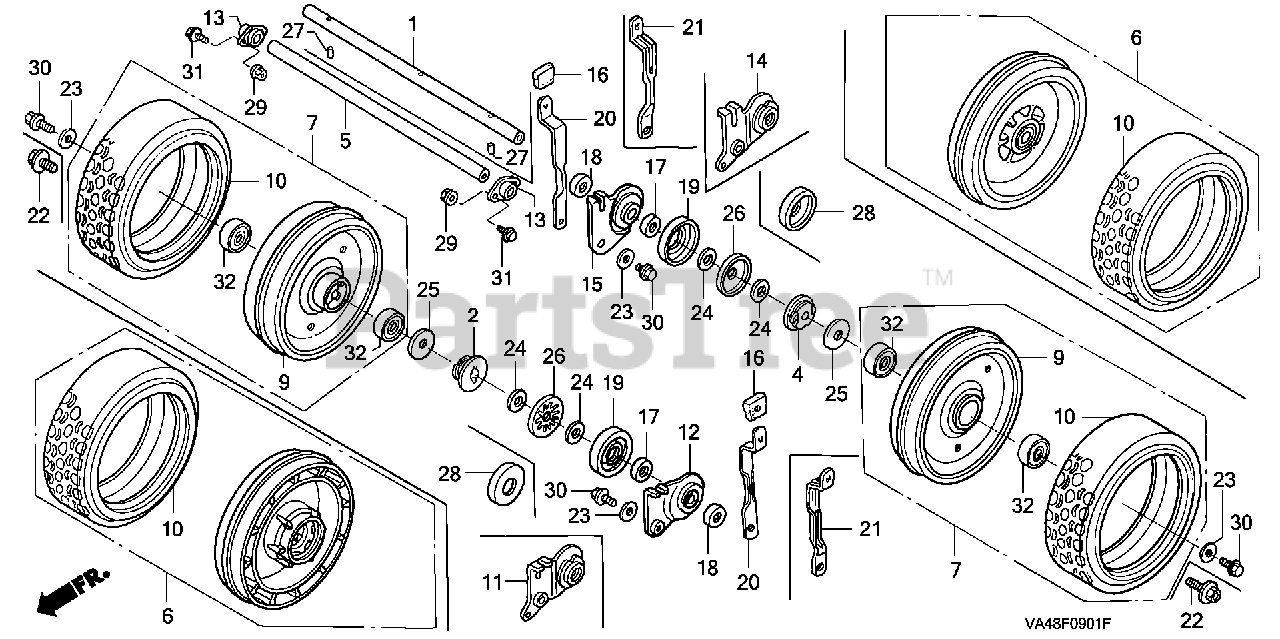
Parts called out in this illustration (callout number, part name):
2	HOLDER, R. RATCHET
4	HOLDER, L. RATCHET
5	SHAFT, RR. AXLE
6	WHEEL ASSY., RR. (9") *NH192M* (GENTLY SILVER METALLIC)
11	ARM, R. RR. ADJUSTER
13	HOLDER, RR. AXLE
14	ARM, RR. ADJUSTER
16	GRIP, ADJUSTER
16	GRIP, ADJUSTER *NH105* (MAT BLACK)
17	COLLAR, DUST SEAL
18	COLLAR, DUST SEAL
20	PLATE, RR. ADJUSTER
23	WASHER, RR. ENGINE MOUNTING
24	WASHER, PLAIN (15MM)
25	WASHER (16MM)
26	SEAL, RR. WHEEL
28	COLLAR, FINAL SHAFT
30	BOLT, FLANGE (8X16) Use from Engine SN 1000016.
31	BOLT, FLANGE (6X12) Use up to Engine SN 1543277.
